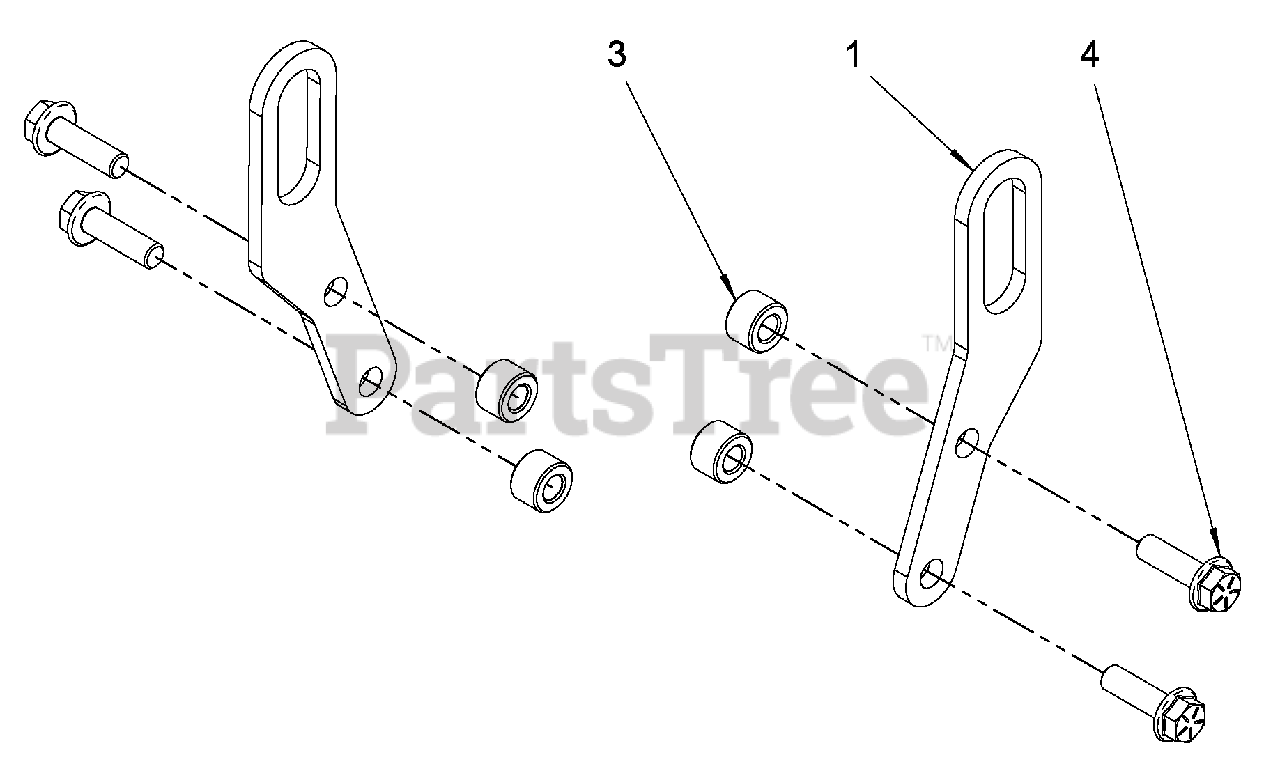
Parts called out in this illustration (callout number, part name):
1	* BRACKET
3	* SPACER
4	* BOLT
